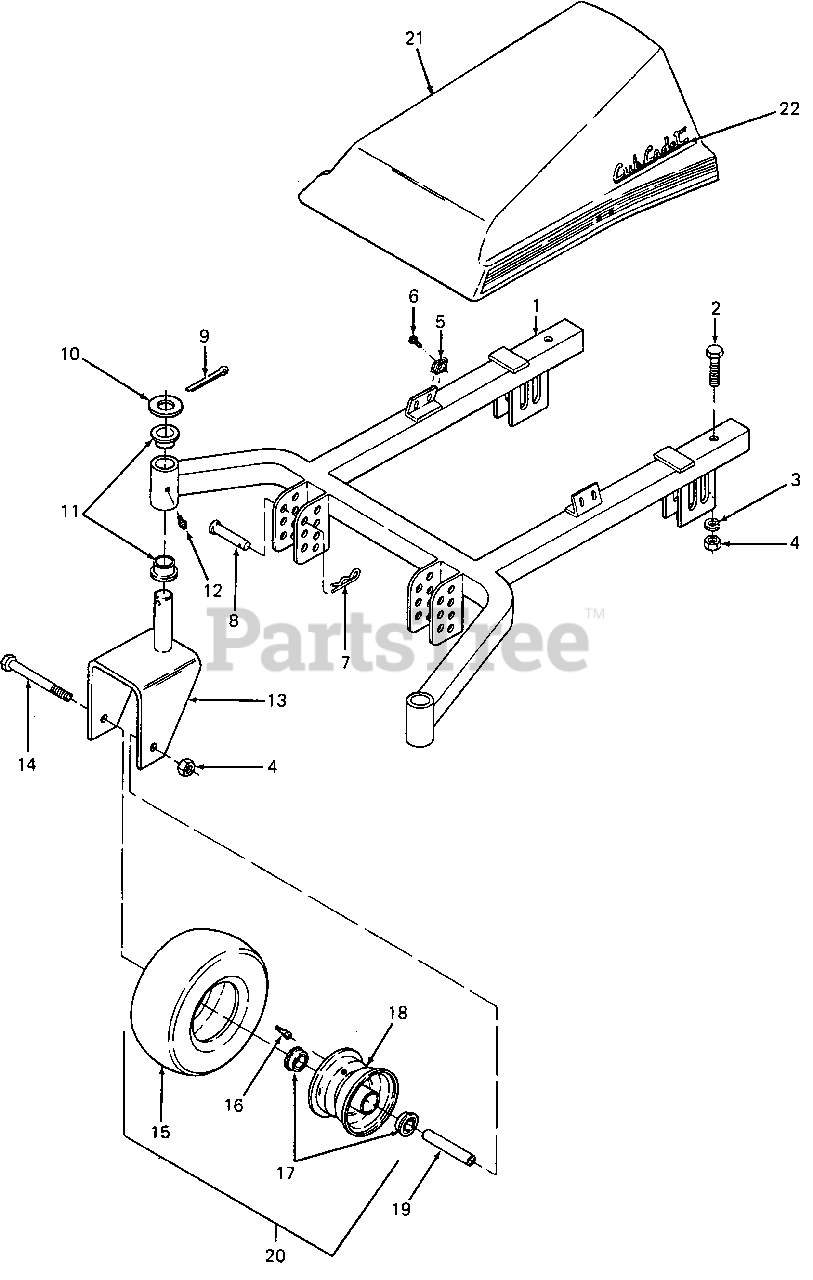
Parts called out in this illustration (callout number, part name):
1	Frame, Mower
2	Screw, Hex Cap, 1/2-13 X 2.0 Lg
3	Washer, Lock, 1/2
4	Nut, Hex Center Lock, 1/2-13
6	Screw, Truss Mach, 1/4-20 X .75 Lg
7	Cotter, Hairpin, 1/8
8	Pin, Clevis, 1/2 Dia X 2.5 Lg
9	Pin, Cotter, 1/4 Dia X 2.0 Lg
10	Washer, Flat, 1" Narrow
11	Bushing, Caster Fork
12	Fitting, Grease, 1/4-28 Str. Short
13	Fork, Caster
14	Screw, Hex Cap, 1/2-13 X 5.0 Lg
15	Tire, Smooth, 3.5-9 X 4
16	Stem, Valve
18	Wheel Assy w/Graphic
19	Spacer, Caster Wheel
20	Wheel Assy, Caster
21	Cover, Mower
22	Script, CCC
